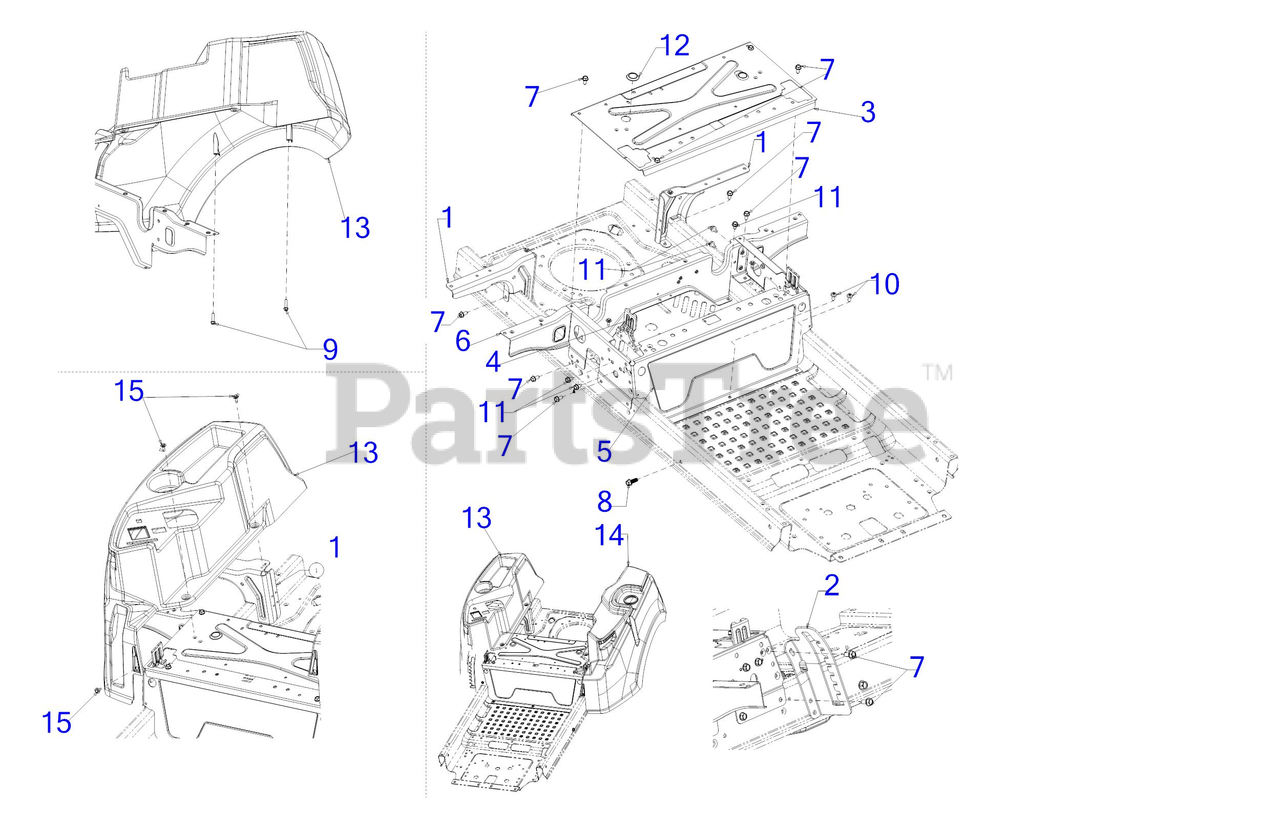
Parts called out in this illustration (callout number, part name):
2	HEIGHT INDEX BRACKET
7	SCREW 5/16-18 x .750
8	SCREW 3/8-16 x 1
9	SCREW 5/16-14 x 1
10	SCREW 5/16-18 x .750
11	SCREW 5/16-18 x .500
13	CONSOLE (RH)
14	CONSOLE (LH)
15	SHOULDER SCREW M6-1 .368 X.115
